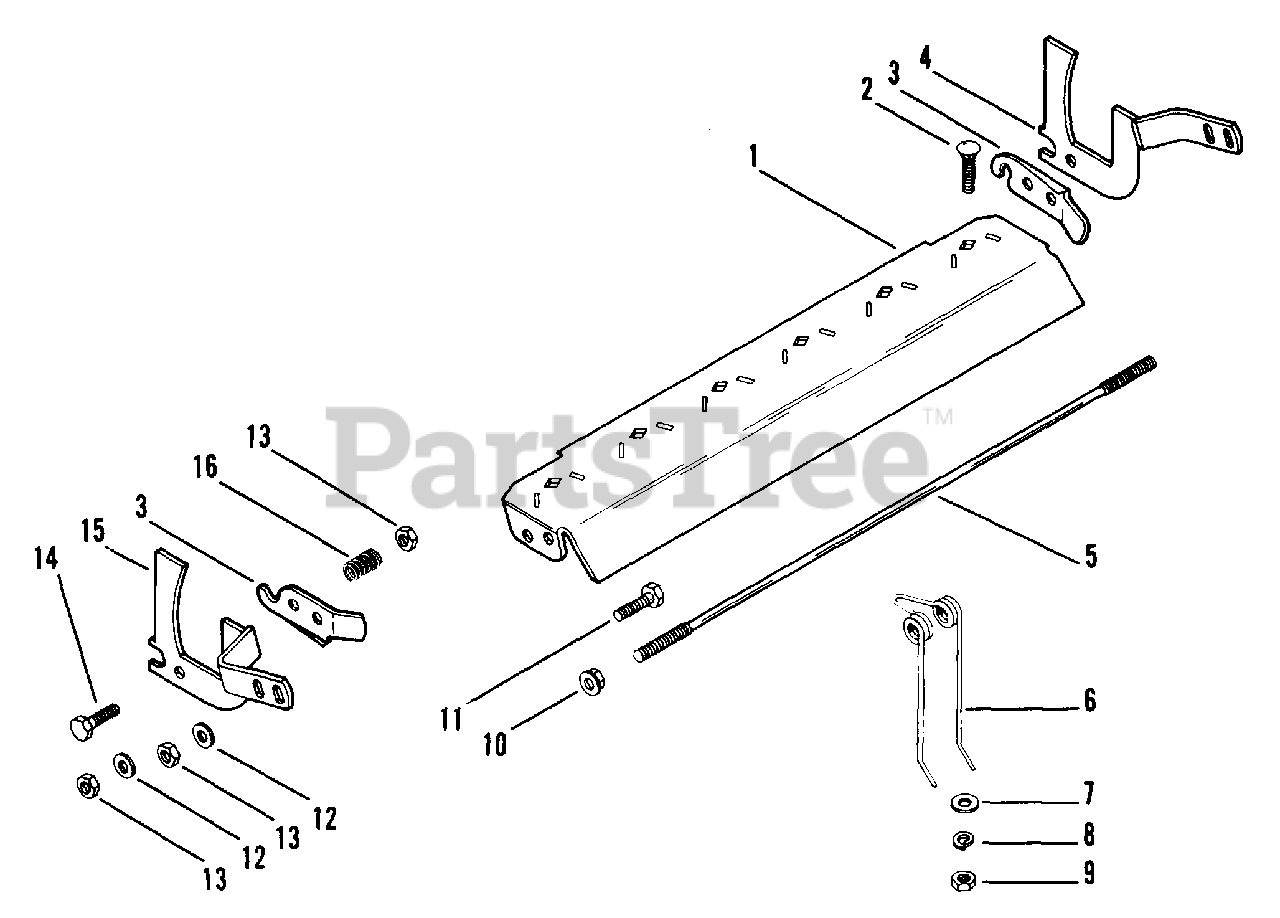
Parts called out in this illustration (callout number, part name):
1	TINE PLATE
2	BLT-RDHDSQNK .31-18X.75 SHT PL
3	AXLE LOCK
4	CAM BRACKET LH
7	WSHR-FL-STL .328X1.0X.094
8	WSHR-LK .312X.097 PL HVY
9	NUT-HEX .312-18
10	NUT-LK-FLG .250-20 PL
11	BLT-HEX .25-20X.75 PL GR2
12	WSHR-FL-STL.281X.62X.065 PL
13	NUT-LK-CTR .250-20 PL
14	BLT-HEX .25-20X1.50 PL GR5
15	CAM BRACKET RH
16	SG-COMP .058X.68X.75
